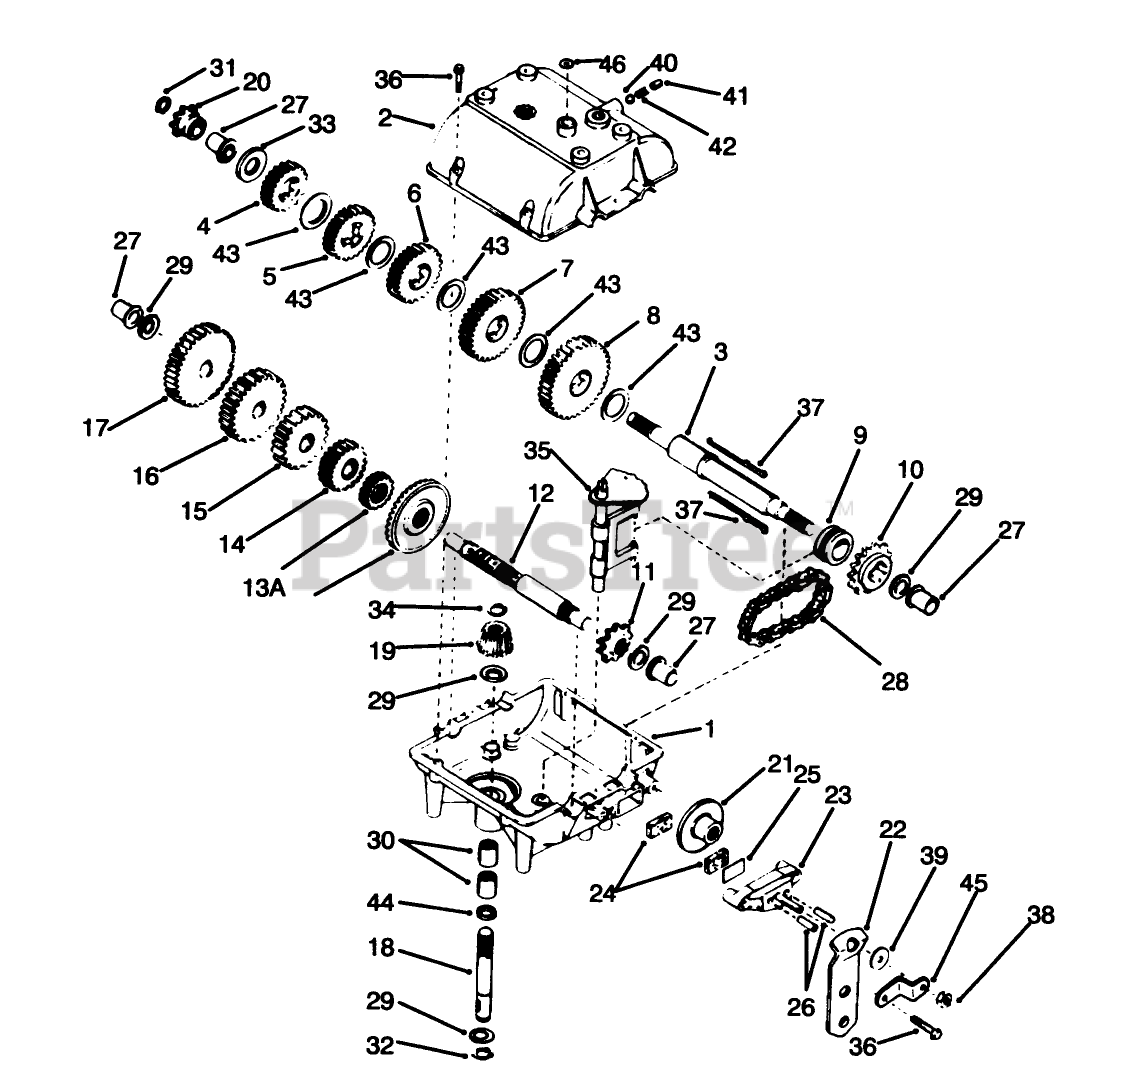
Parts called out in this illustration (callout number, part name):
1	Case-Transmission
2	Cover-Transmission
3	Shaft-Output
4	Gear-Spur 20 teeth
5	Gear-Spur (22 teeth)
6	Gear-Spur, 25 Teeth
7	Gear-Spur, 30 Teeth
8	Gear-Spur, 35 Teeth
9	Collar-Shift
10	Sprocket-18 Teeth
11	Sprocket-9 Teeth
12	Countershaft
13	Gear-Bevel (42 Teeth)
13A	Gear-Spur 15 Teeth
14	Gear-Spur, 20 Teeth
15	Gear-Spur, 25 Teeth
16	Gear-Spur (28 teeth)
17	Gear-Spur (30 teeth)
18	Shaft-Input
19	Bevel Pinion-Input
20	Sprocket (8Teeth)
22	Lever-Brake
23	Nozzle-Carburetor
24	Brake Pad
25	Brake Pad Plate
26	Dowel Pin
27	Bushing-Flange
28	Chain-Roller #41
29	Washer
30	Bearing-Needle
31	Piston Asm (.020 O S)
32	Ring-Snap
33	Washer
34	Ring-Retainer
35	Rod and Fork ASM
36	Ring Set (.020 O S)
38	Locknut
39	Washer
40	Ball-Steel
41	Screw-Set
42	Spring
43	Washer
44	O Ring
45	Bracket
46	Cut Seal-Square
